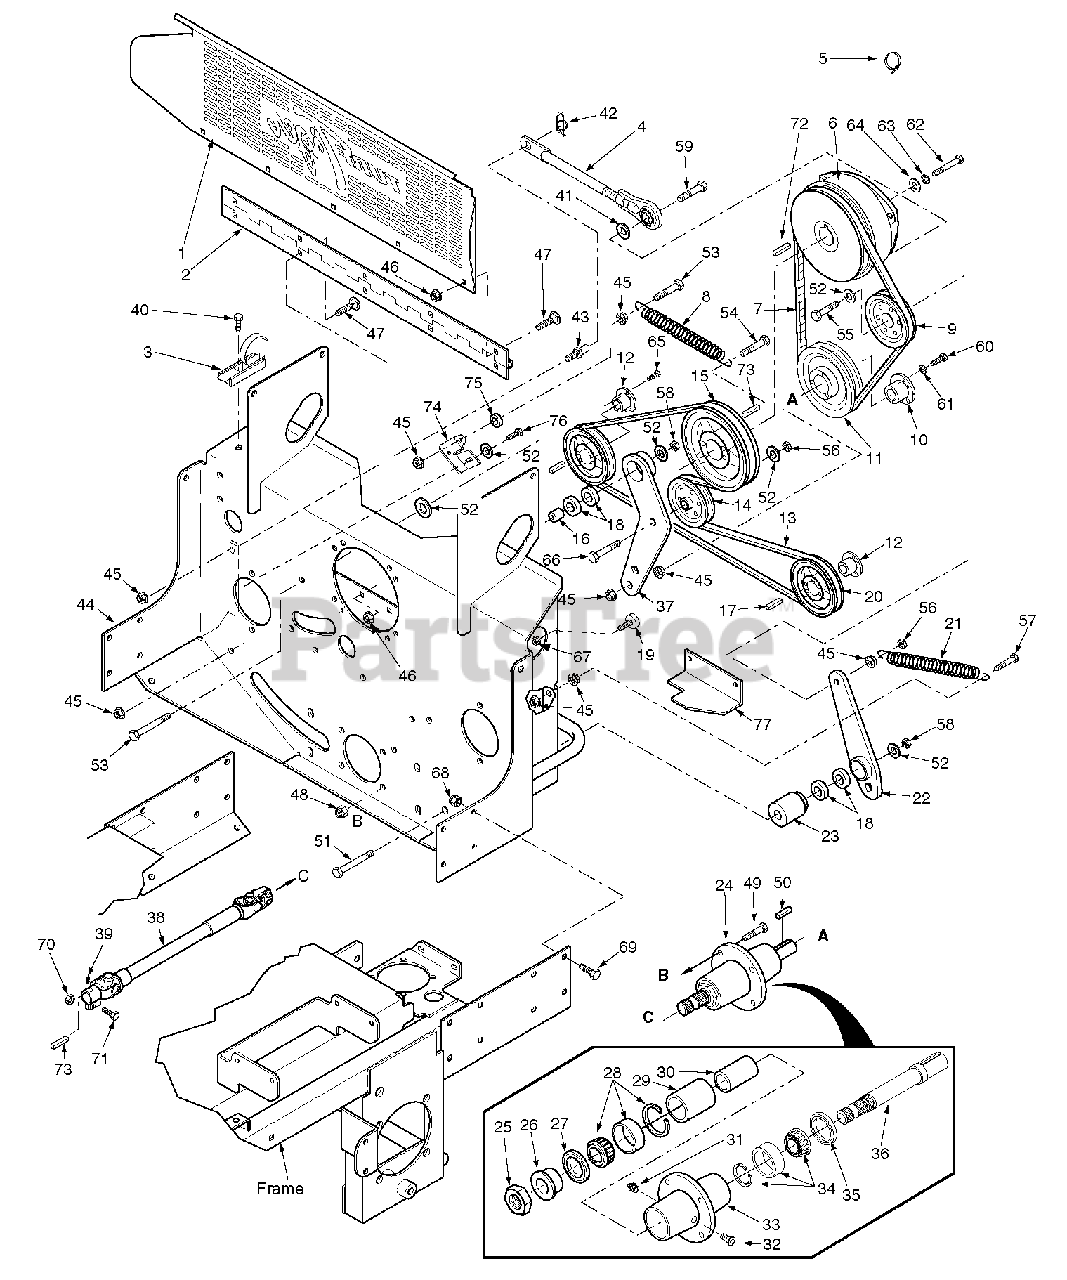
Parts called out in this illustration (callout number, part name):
1	Belt Guard, Rear
2	Hinge, Belt Guard
3	Latch, Hood
4	Rod Assembly, Clutch Anti-Rotation
5	Clamp, Cable
6	Clutch, Ogura GT-3.5
6	Clutch, Ogura GT-5 (35BVAC)
7	Belt, Deck Drive
8	Spring, Transmission Idler
9	Pulley, Idler 5" Dia.
10	Tapered Hub, 1" Bore
11	Pulley, 6.70" Tapered Bore
12	Tapered Hub, 17mm Bore
13	Belt, Pump Drive STT
13	Belt, Pump Drive (791DFI, 29EFI, 35BVAC)
14	Pulley, Idler 4" Dia.
15	Pulley, 4.55" Dia.-1.125" Bore
15	Pulley, 5.15" Dia.-1.125" Bore (791DFI, 35BVAC)
16	Spacer, Idler Bearing
17	Key, 5.0 x 5.0 x 25mm
18	Ball Bearing
19	Bumper, Rubber
20	Pulley, 6.35" O.D.
21	Spring, PTO
22	Idler Arm Weldment, PTO Drive
23	Pivot, Idler PTO
24	Spindle Assembly, Deck Drive
25	Nut, 1.06"-18 Thread
26	Spindle Bushing, Bottom
27	Seal, 2.0" OD x 1.625" Bore
28	Roller Bearing Tapered
29	Spacer, Outside
30	Spacer, Inside
31	Grease Fitting, 1/4-28
32	Relief Fitting
33	Spindle Housing
34	Roller Bearing Tapered
35	Seal, 2.0" OD x 1.5" Bore
36	Shaft, Deck Drive
37	Idler Arm Weldment, Pump Drive
38	Driveshaft (Air-Cooled Engine)
38	Driveshaft (Liquid-Cooled Engine & 35BVAC)
39	Set Screw, 3/8-16 x 3/4" Torx Socket
40	Screw, #10-32 x .56"
41	Flatwasher, 3/8 (.391 x .938 x .105")
42	Pin, Rue Cotter 3/8" Dia.
43	Stud, Anti Rotation
44	Pump Mounting Plate Weldment (Liquid-Cooled Kawasaki)
44	Pump Mounting Plate Weldment (Air-Cooled 29EFI Kohler)
44	Pump Mounting Plate Weldment (Air-Cooled Briggs & Stratton)
45	Nut, Serrated Flange 3/8-16
46	Nut, Serrated Flange 1/4-20
47	Bolt, Carriage 1/4-20 x 1/2"
48	Nut, Elastic Stop 5/16-18
49	Bolt, Hex Head 5/16-18 x 1-3/4"
50	Key, 1/4 x 1/4 x 1-1/2"
51	Bolt, Hex Head 3/8-16 x 4-1/2" Grd 8 Black
52	Washer, 3/8" Hardened
53	Bolt, Hex Head 3/8-16 x 1-3/4" Grd 8 Black
54	Bolt, Hex Head 3/8-16 x 1-1/2" Grd 8 Black
55	Bolt, Hex Head 3/8-16 x 2-1/2" Grd.8
56	Nut, Center Lock 3/8-16
57	Bolt, Hex Head 3/8-16 x 1-1/2" Grd 8 Black
58	Nut, Elastic Stop 3/8-16
59	Bolt, Hex Head 3/8-16 x 2"
60	Bolt, Hex Head 1/4-20 x 1-3/8"
61	Lockwasher, 1/4" Spring
62	Bolt, Hex Head 7/16-20 x 2-1/2" UNF
63	Lockwasher, 7/16" Spring
64	Flatwasher, 7/16 (.469 x 1.75 x .25")
65	Bolt, Hex Head 1/4-20 x 1"
66	Bolt, Hex Head 3/8-16 x 1-3/4"
67	Nut, Serrated Flange 5/16-18
68	Nut, Elastic Stop 3/8-16
69	Bolt, Hex Head 3/8-16 x 1"
70	Nut, Center Lock 3/8-16
71	Bolt, Hex Head 3/8-16 x 1-3/4"
72	Key, 1/4 x 1/4 x 2-1/4"
73	Key, 1/4 x 1/4 x 1"
74	Bracket
75	Spacer
76	Bolt, Hex Head 3/8-16 x 1"
77	Bracket, Idler Stop
